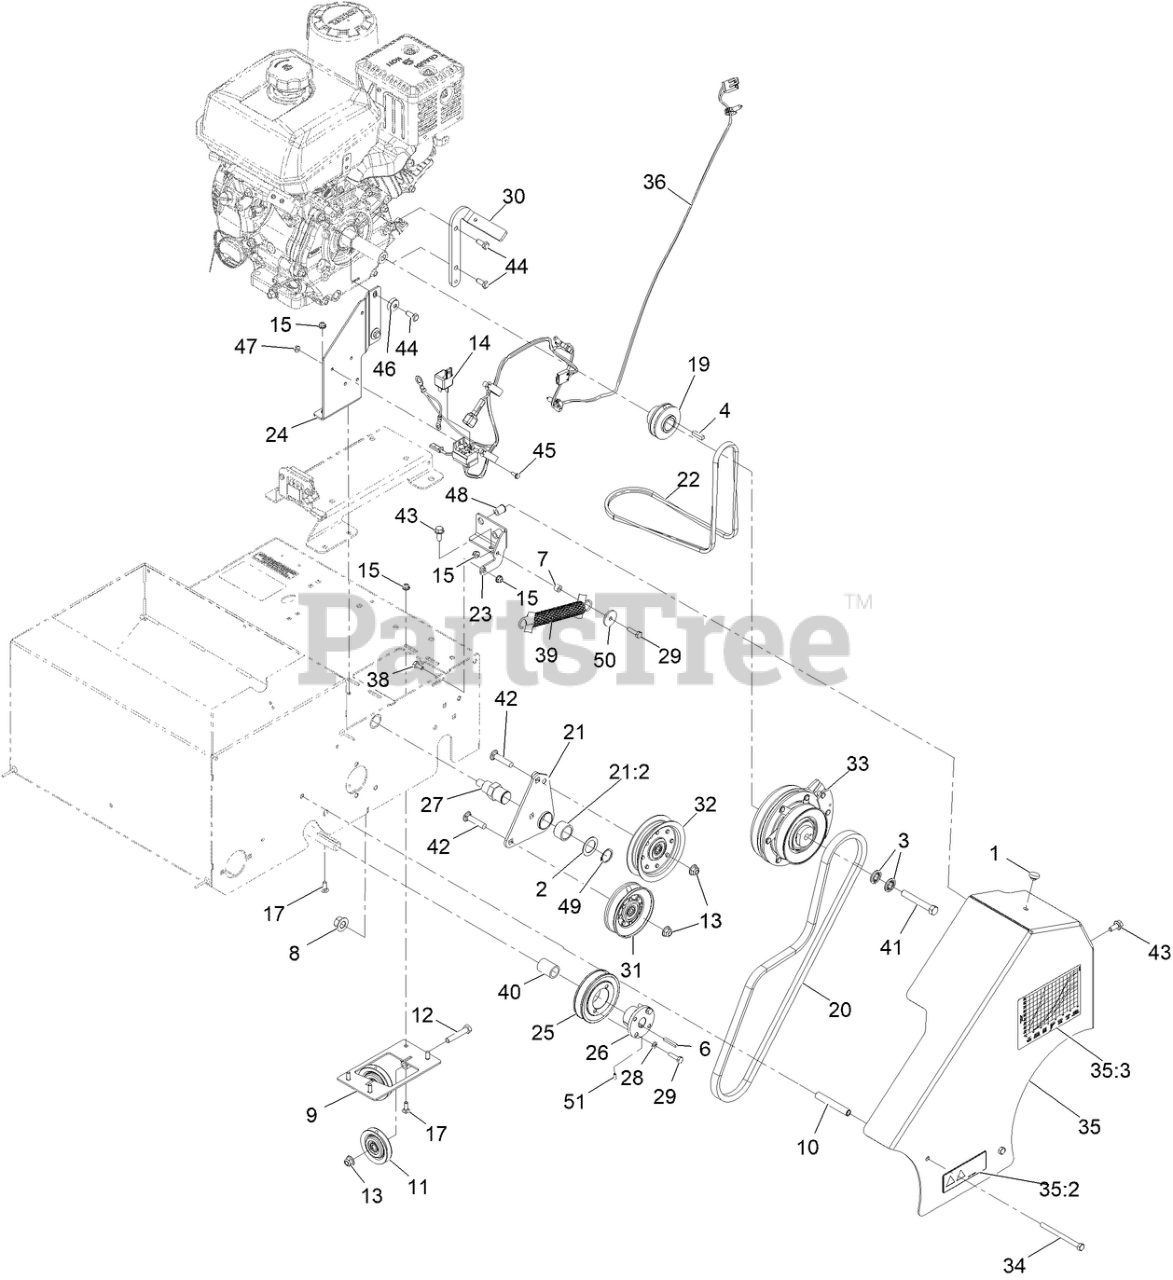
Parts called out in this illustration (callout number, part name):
2	WASHER-SPACER
3	WASHER-SPRING
6	KEY-SQUARE
8	Nut-Lock 1/2-13
9	PULLEY-TENSION
10	SPACER-KICKSTAND, LONG
11	PULLEY-IDLER
12	SCREW-HH
13	NUT-HF, NI
17	BOLT-CARR
19	PULLEY-MULE DRIVE
20	BELT-SEEDER, CLUTCH
21	IDLER ARM ASM
21:2	BUSHING
22	BELT-MULE DRIVE
23	BRACKET-SPRING
24	GUARD-BELT
25	SHEAVE-TAPER LOCK
26	BUSHING-TAPER LOCK
27	PIVOT-IDLER
28	WASHER-LOCK
29	SCREW-HH
30	STOP-CLUTCH
31	PULLEY-IDLER V
32	PULLEY-IDLER FLAT (4.06-I
33	CLUTCH-ELECTRIC
34	SCREW-HH
35	GUARD-BELT, W/DECALS
35:2	DECAL-DANGER
35:3	DECAL-GRAPH, SEED
36	HARNESS-WIRE
38	SCREW-HH
39	SPRING-EXTENSION
41	SCREW-HH
42	SCREW-CARR
43	SCREW-HHF
44	SCREW-HH
45	SCREW-HWH
46	WASHER-BELLEVILLE
47	NUT-LOCK, FLANGE
48	NUT-CLINCH
49	RING-RETAINING
50	WASHER
51	SCREW-SET, HS
